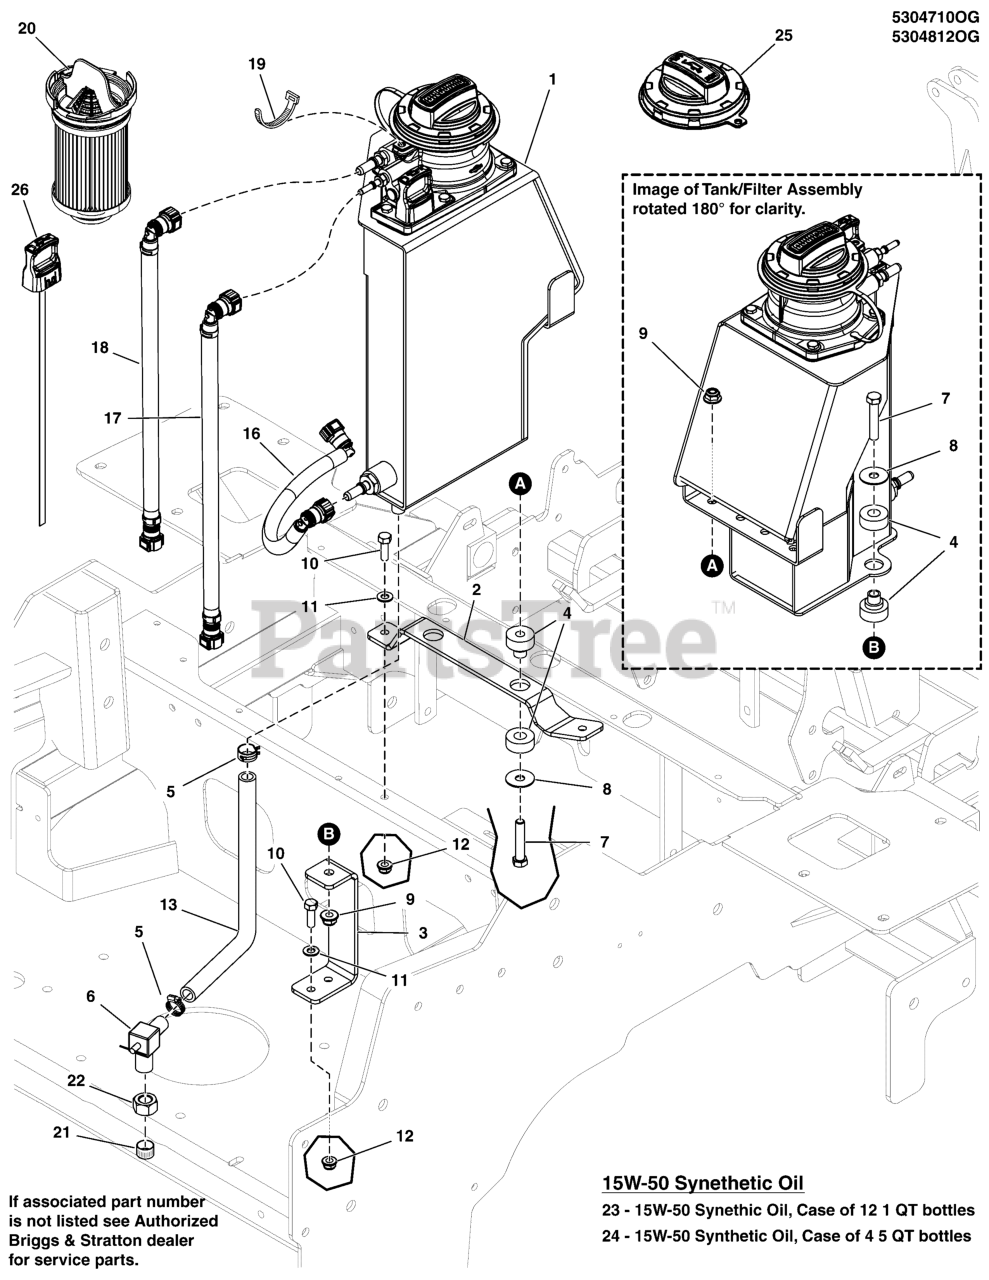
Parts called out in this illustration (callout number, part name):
1	TANK, Oil
1	TANK, OIL
2	TANK MOUNT, FRONT, 3200 - BLK
3	TANK MOUNT, LOWER, 3200 - BLK
4	MOUNT, ISO, BOTTOM, RAD 5000Z-DIESEL
5	CLAMP, #6 HOSE, STAINLESS
6	VALVE, OIL DRAIN, M16X1.5 TO 1/2"
7	BOLT, 3/8-16 X 1-3/4" GD5 CZ
8	WASHER, 3/8" Fender
9	NUT, 3/8 - 16 HEX NYLOCK FLANGE
10	BOLT, 5/16-18 X 1" GRD5 YZ
11	WASHER, 5/16" SAE
12	NUT, 5/16-18 HEX NYLOCK FLANGE NUT
13	HOSE, Formed, Oil Guard
16	HOSE, OIL SUPPLY
17	HOSE, Oil Vent
18	HOSE, OIL SCAVENGE
20	FILTER, OIL
21	OIL DRAIN CAP, OIL GUARD, DAPCO 4692
22	NUT, HEX, M16-1.5, DAPCO 4071
23	OIL, 15W-50, SYNTHETIC, CASE X 12- 1QT
24	OIL, 15W-50, SYNTHETIC, CASE X 4- 5QT
25	CAP, Oil Fill
26	DIPSTICK
